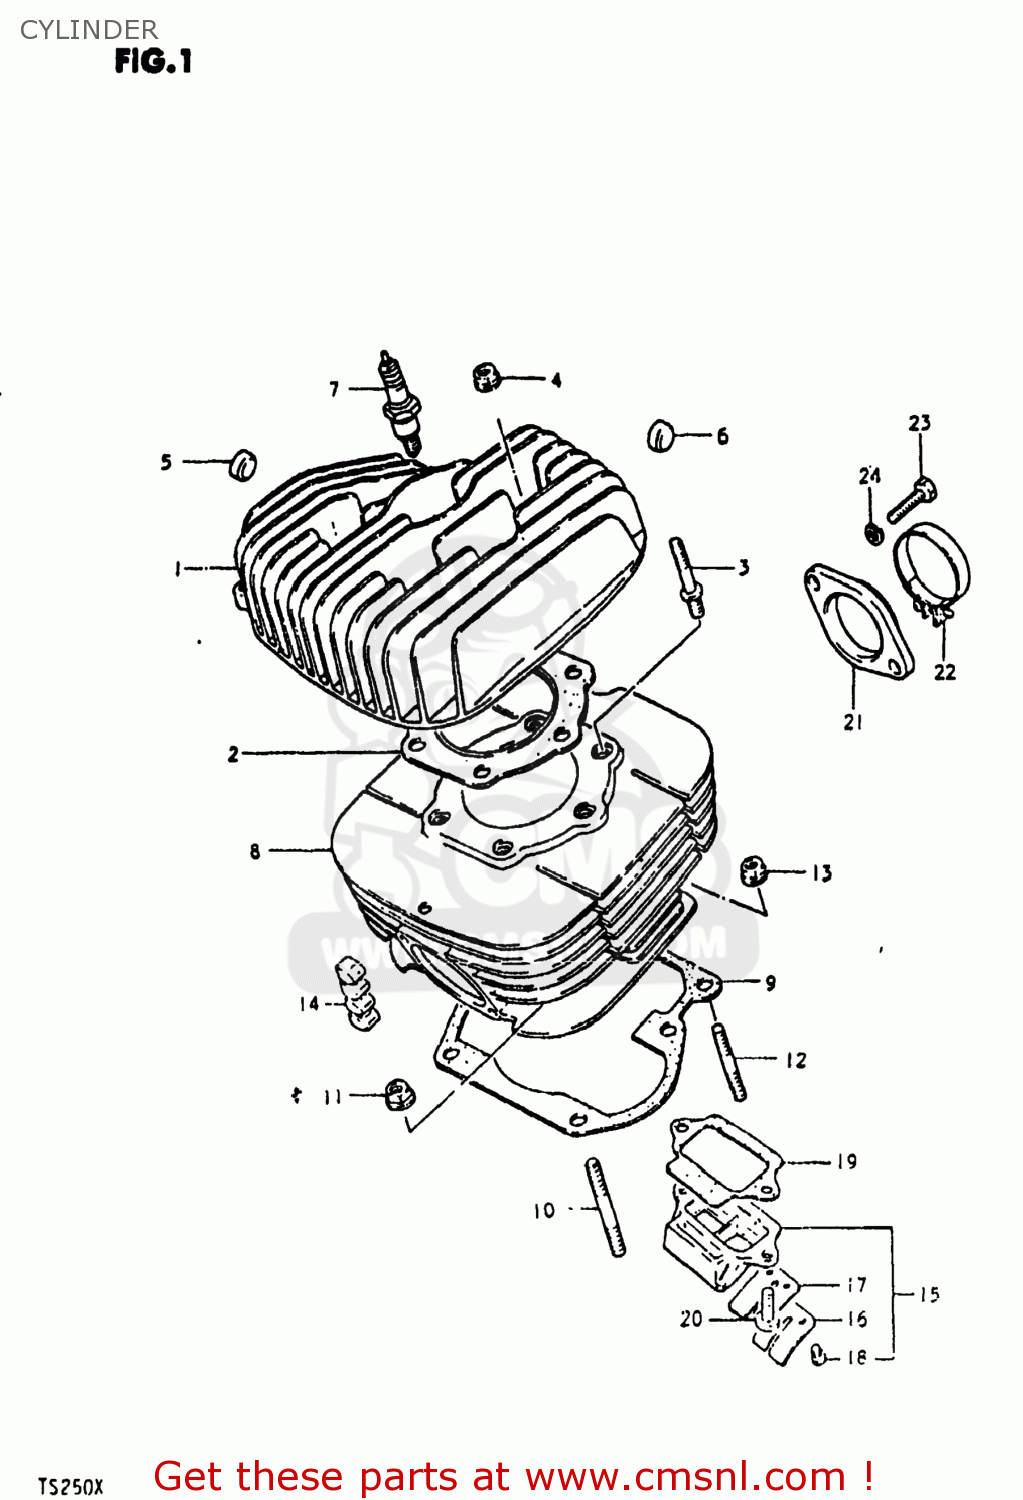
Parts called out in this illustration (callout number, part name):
1	HEAD,CYLINDER
2	GASKET,CYLINDER HEAD (NAS)
3	BOLT,STUD
4	NUT
5	PAD,CYLINDER
6	PAD,CYLINDER HEAD
7	SPARK PLUG
8	CYLINDER
9	GASKET,CYLINDER (MCA)
10	STUD 10X25
11	NUT
12	STUD 8X25
13	NUT
14	PAD,CYLINDER
15	VALVE ASSY,REED
16	STOPPER,REED VALVE
17	VALVE,REED
18	SCREW,REED VALVE
19	GASKET,REED VALVE (MCA)
20	SCREW
21	PIPE,INTAKE
22	CLAMP
23	BOLT, UPPER
24	LOCK WASHER
